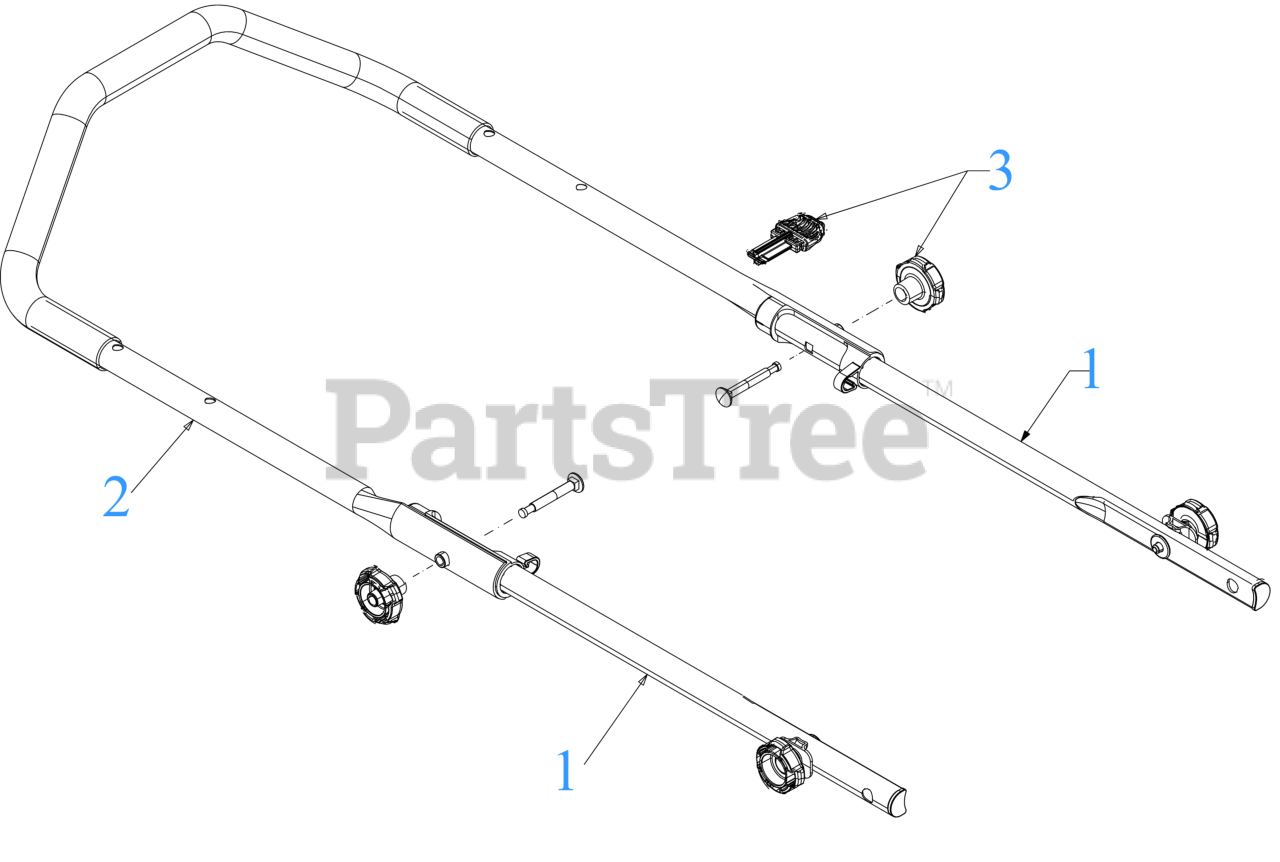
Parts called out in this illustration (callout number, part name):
1	HANDLE (LOWER)
2	HANDLE (UPPER)
3	HARDWARE KIT (KNOB/KEY) (YELLOW)
